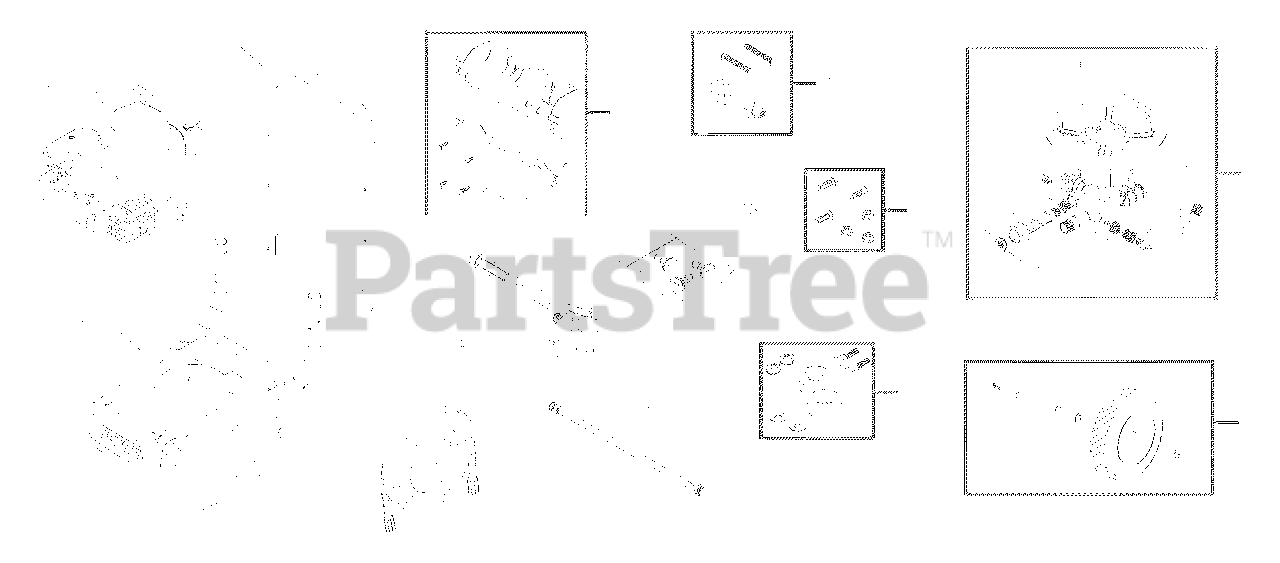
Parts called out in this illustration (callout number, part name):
2	HANDLE
3	KIT, Billboard w/Decals
4	KIT, Handle Connector
6	Kit, Chemical Hose
8	Valve, Thermal Relief
9	Kit, Chemical Injection
10	Kit, Water Inlet
12	KIT, Pump Mounting Hardware
13	KIT, Spray Tips
14	GUN
15	HOSE
16	EXTENSION, QC
17	KIT, Vibration Mount
